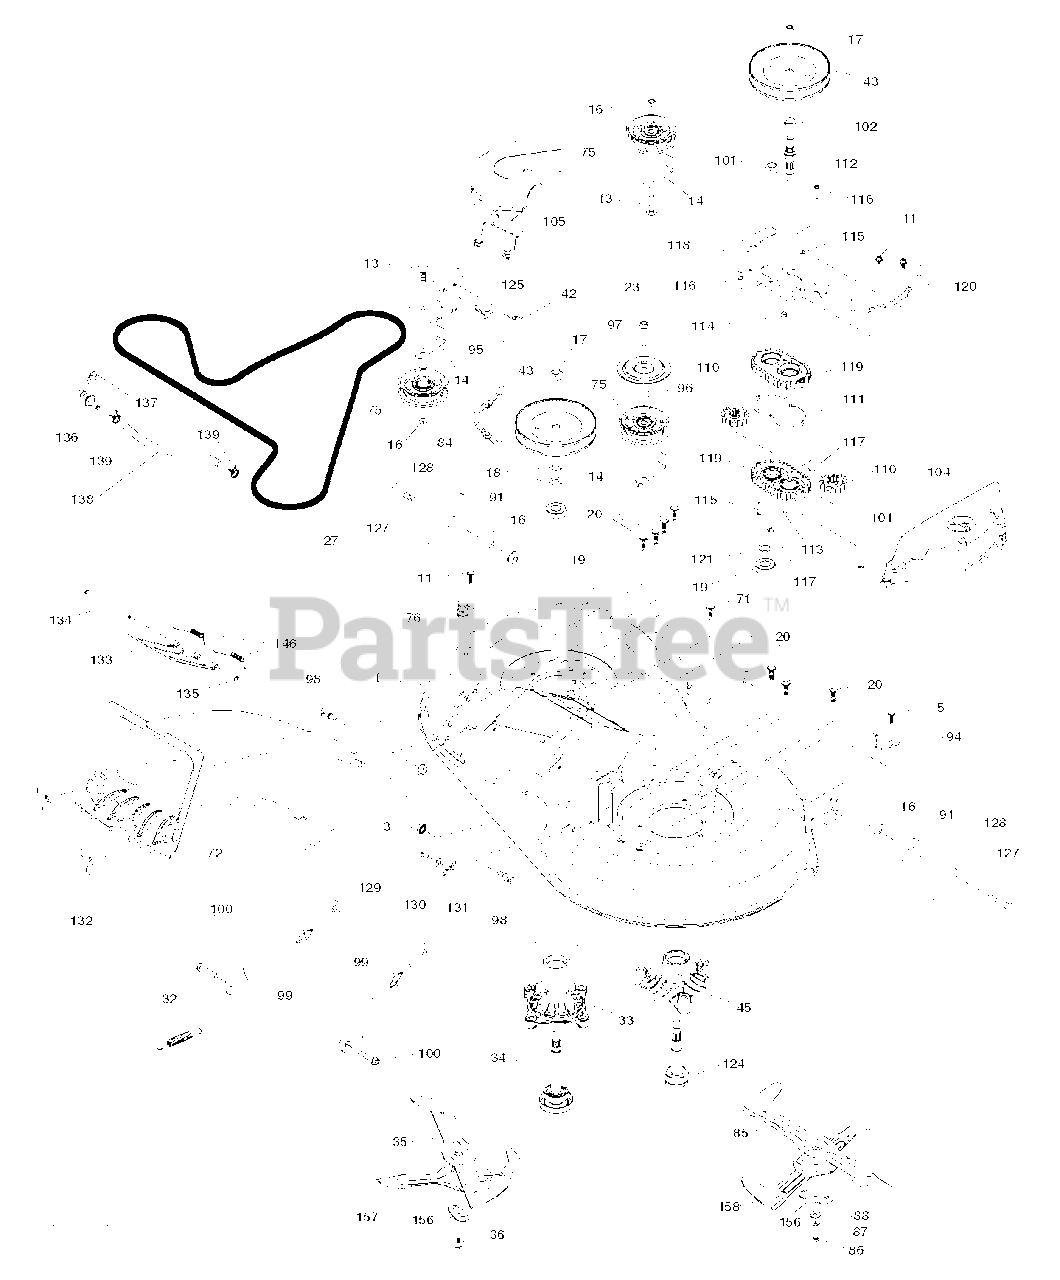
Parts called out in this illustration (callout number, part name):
3	NUT LOCK HEX FLANGE 5/16-18
5	BOLT.5/16HEX.WHS.HD
11	SCREW.1/4-20X5/8
13	BOLT.3/8-16X1.50
14	KEEPER, BELT IDLER
16	NUT LOCK FLG 3/8-16 UNC
17	NUT.FLANGE.LOCK.TOP
18	WASHER.SPACER.MANDREL
20	SCREW, WASHER HEAD
23	SCREW LT
27	BELT BELT. ELECTRIC MOWER DRIV
32	SPRING 107CM & 97CM ELECTRIC D
33	HOUSING.MANDREL.4PT.
34	SHAFT.ASM.MDRL.N/GREASE.38
35	BLADE.3N1.LH.CRD
36	BOLT.WASHER.ASM.7/16-2
42	SCREW
43	PULLEY PULLEY MANDREL 5.438 PD
45	HOUSING.MANDREL.44/46" VENT
71	SCREW 3/8-16X1/2
72	RP 97107.TEX.CRD.UPPE
75	FLAT IDLER PULLEY
76	PORT.WASHOUT
84	KEEPER KEEPER. LH MANDREL BELT
85	BLADE.3N1.RH.CRD
86	BOLT.3/8-24X1.25GR8. LHTHRD
87	LOCKWASHER
88	WASHER.BLADE
91	WASHER
94	BRKT.CLUTCH.CABLE
95	SCREW, 3/8-16X3/4
96	SPACER
97	PROTECTOR
98	STUD.FASTNER.W/ANTI-ROTATE
99	ARM.SUSPENSION.MOWER.R
100	BOLT.SHOULDER
101	NUT.CROWNLOCK.9/16 -18.UNC
102	SPACER BEARING
110	GEAR GEAR OUTPUT
111	GASKET GASKET GEARCASE
112	SHAFT SHAFT. CRD GEARCASE ADAP
113	PLUG PLUG OIL
114	VALVE VALVE RELIEF
115	SCREW
116	BOLT.CARIGE.SS.1/4-20X1.75GR5
117	NUT T
118	ARM ARM. CLUTCHING 107 TEX CRD
119	GEARCASE GEARCASE SUBASM
120	KEEPER KEEPER. RH MANDREL BELT
121	WASHER WASHER
124	MANDREL SHAFT NON/GREASE
125	BRACKET BRACKET IDLER CHASSES
127	BOLT.SHOULDER.3/8-16X3-5/8.
128	WHEEL. GUAGE RALLY
129	ROD ROD. SWAY CRD GEN II
130	WASHER
131	PIN.COTTER.5/16.BOW TI
132	KNOB.HANDLE.3/8.TRI-POINT.BLAC
133	COVER DOOR.107 CM CRD EZ MULCH
134	PIN PIN.HINGE
135	E-RING.5/16"
136	PLUG WASHOUT PORT HOOKUP
138	107.WASHOUT.PORT.HOSE (2 2)
139	HOSE.3/8.CLAMP (2 2)
146	SPRING SPRING: EZ MULCH DOOR
156	ADAPTER ADAPTER.CROSSBLADE.107
157	BLADE 107CM.CROSS.BLADE
158	BLADE.CROSS.RH.CRD.107
